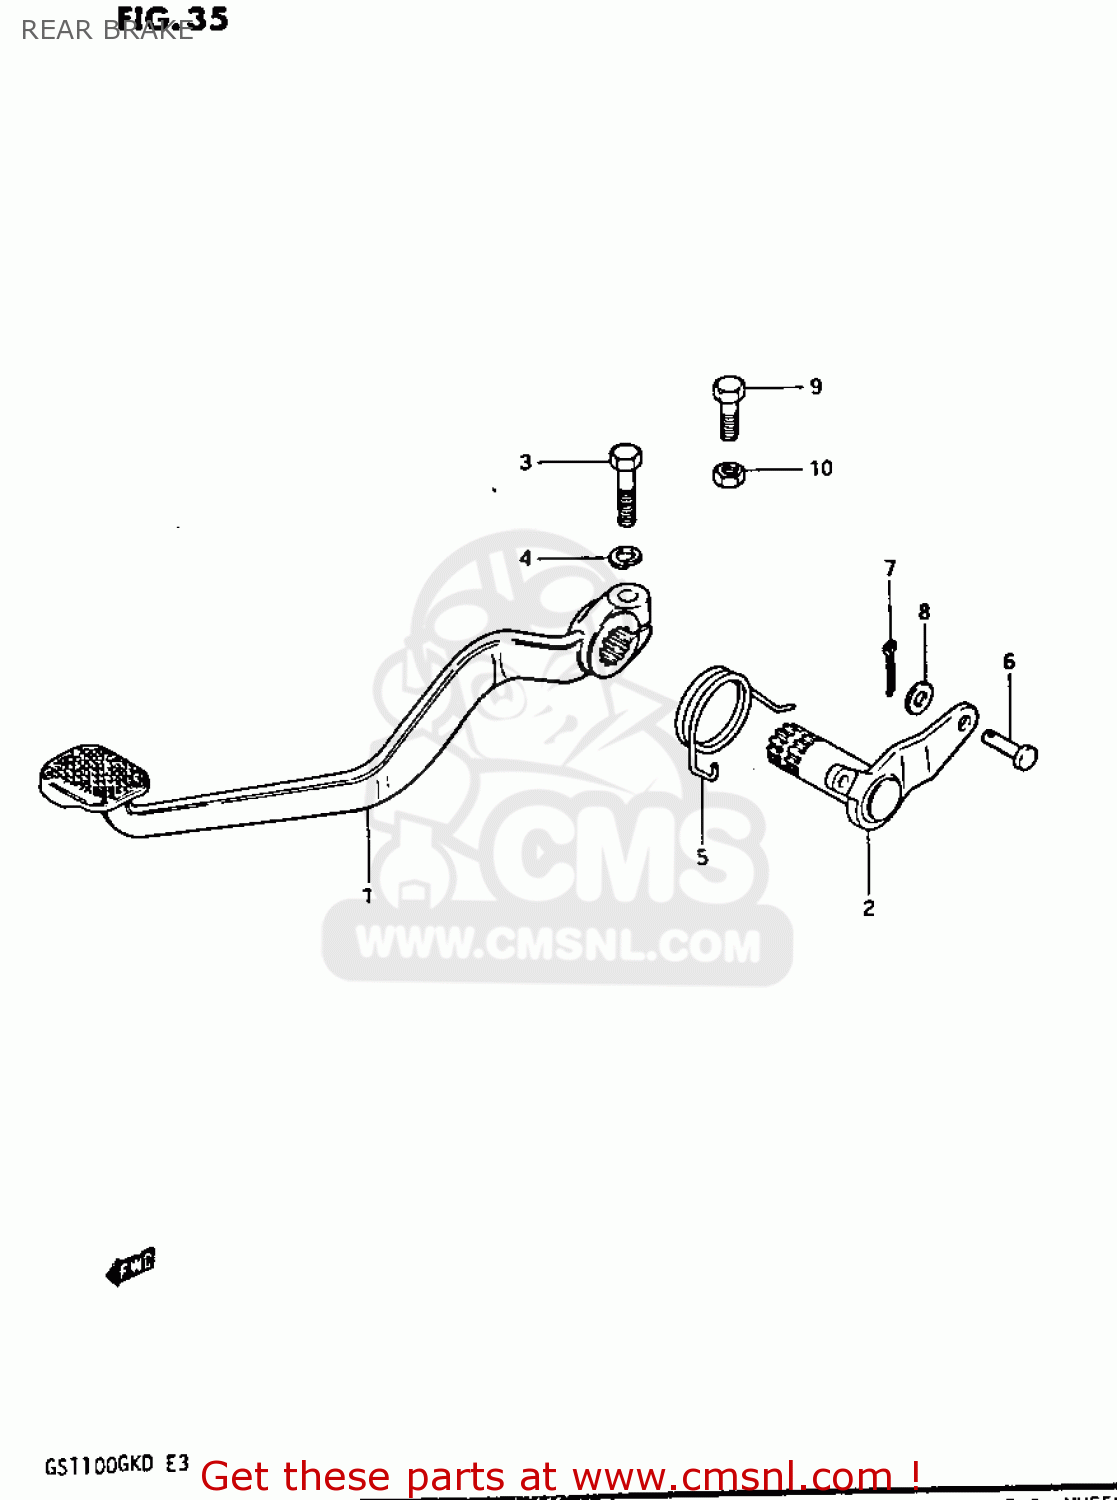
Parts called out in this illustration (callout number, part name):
1	PEDAL,BRAKE
2	ARM,BRAKE PEDAL ROD
3	BOLT
4	LOCK WASHER
5	SPRING
6	PIN
7	PIN
8	WASHER
9	BOLT
10	NUT
